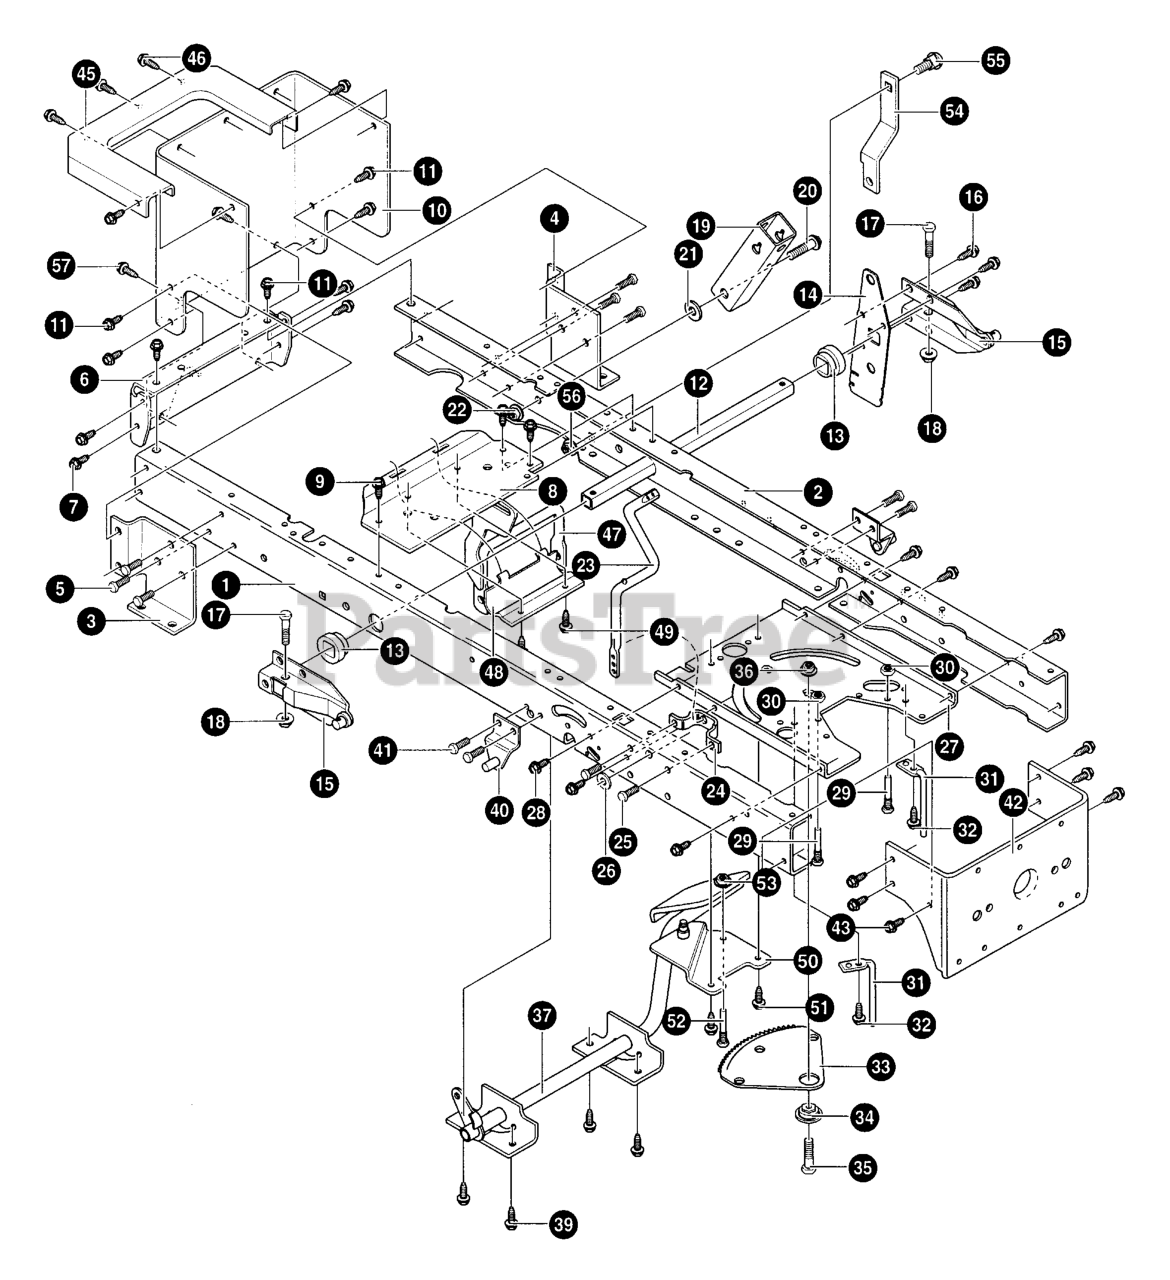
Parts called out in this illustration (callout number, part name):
1	FRAME, RAIL RH
2	FRAME, RAIL LH
3	BRACKET, TRANSAXLE RH
4	BRACKET, TRANSAXLE LH
5	SCREW, 5/16-18 x 0.75
6	HITCH PLATE
7	SCREW, 5/16-18 x 0.75
8	BRACKET, IDLER SUPPORT
9	SCREW 5/16- 18X.75
10	PLATE, REAR
11	SCREW, 5/16-18 x 0.75
12	TUBE, LIFTER
13	BUSHING, LIFT TUBE
14	PLATE- LIFT ARM
15	ASSY LIFT ARM LEVER
16	SCREW, 5/16-18 x 0.50
17	SCREW, 5/16-24 x 1.25
18	NUT, 5/16- 24
19	BRACKET, PIVOT
21	FLATWASHER
22	NUT, 3/8- 16
23	CRANK, PTO (DRILLED)
24	BRACKET, BELLCRANK
25	SCREW, 5/16-18 x 0.75
26	FLATWASHER
27	PLATE, STEERING MOUNT
28	SCREW, 5/16-18 x 0.75
29	SCREW GUIDE 5/16- 18
30	NUT, 5/16- 18
31	ROD, BELT GUIDE
32	SCREW
33	SECTOR GEAR
34	BEARING, SECTOR GEAR
35	CAPSCREW, Hex Head, 5/16-18 x 1
36	NUT, 5/16- 8
37	ASSEMBLY, BRAKE LEVER
39	SCREW, 5/16-18 x 0.75
40	BRACKET, SUSPENSION
41	SCREW, 5/16-18 x 0.75
42	BRACKET, HANGER REAR
43	SCREW, 5/16-18 x 0.75
45	TOP, REAR PLATE
46	SCREW 10- 24X.5
47	YOKE ASSY
48	CLAMP, TRUNNION PIVOT
49	SCREW, 51/6- 18X.75
50	ASSY, IDLER INTERMEDIATE
51	BOLT, 5/16- 18X0.5
52	SCREW GUIDE
53	NUT, 5/16- 18
54	BRACKET, Torque Strap, LH
55	BOLT, 5/16- 18X0.63
56	NUT, 5/16- 18
